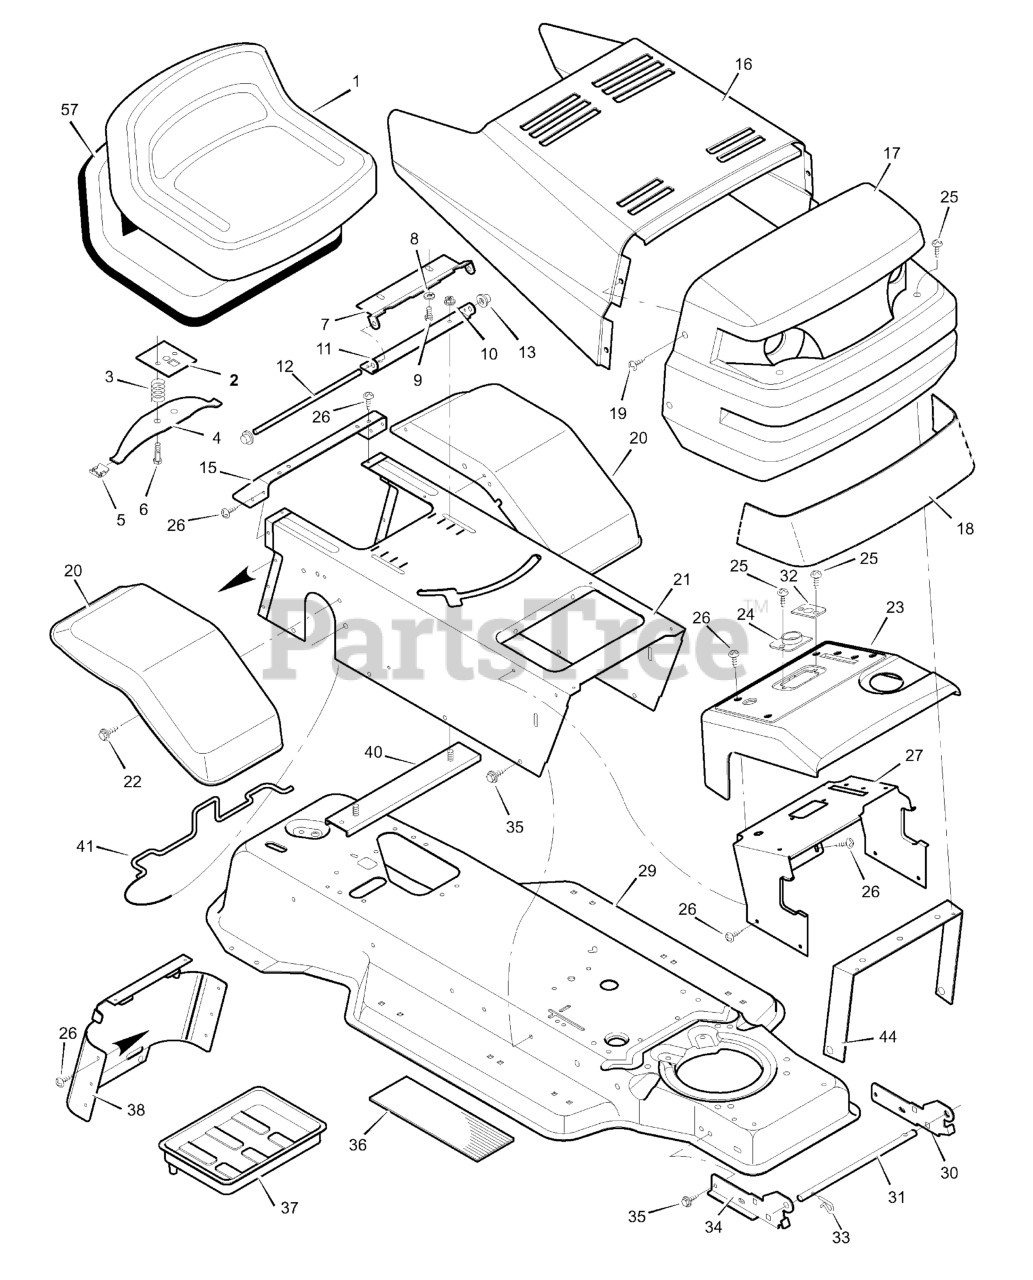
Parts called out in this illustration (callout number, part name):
2	Plate Assembly, Switch
3	Spring, Compression
4	Spring, Seat
5	Glide, Spring
6	Bolt, Shoulder
7	Support, Seat
8	Lockwasher
9	Bolt, Hex
10	Locknut, Flange
11	Bracket, Pivot
12	Rod, Pivot
13	Cap, Push On
15	Fender, Apron
17	Grille Assembly
21	Console Assembly
23	Dash Panel
24	Bearing, Steering
26	Screw
27	Support, Dash
29	Frame Assembly
30	Bracket, Left Grille
31	Rod, Pivot
32	Bearing
33	Pin, Hair
34	Bracket, Right Grille
37	Tray, Battery
38	Cap, Console
39	Bolt
40	Channel Assembly
41	Clamp, Battery
44	Brace, Grille
57	Pan, Seat (with foam)
